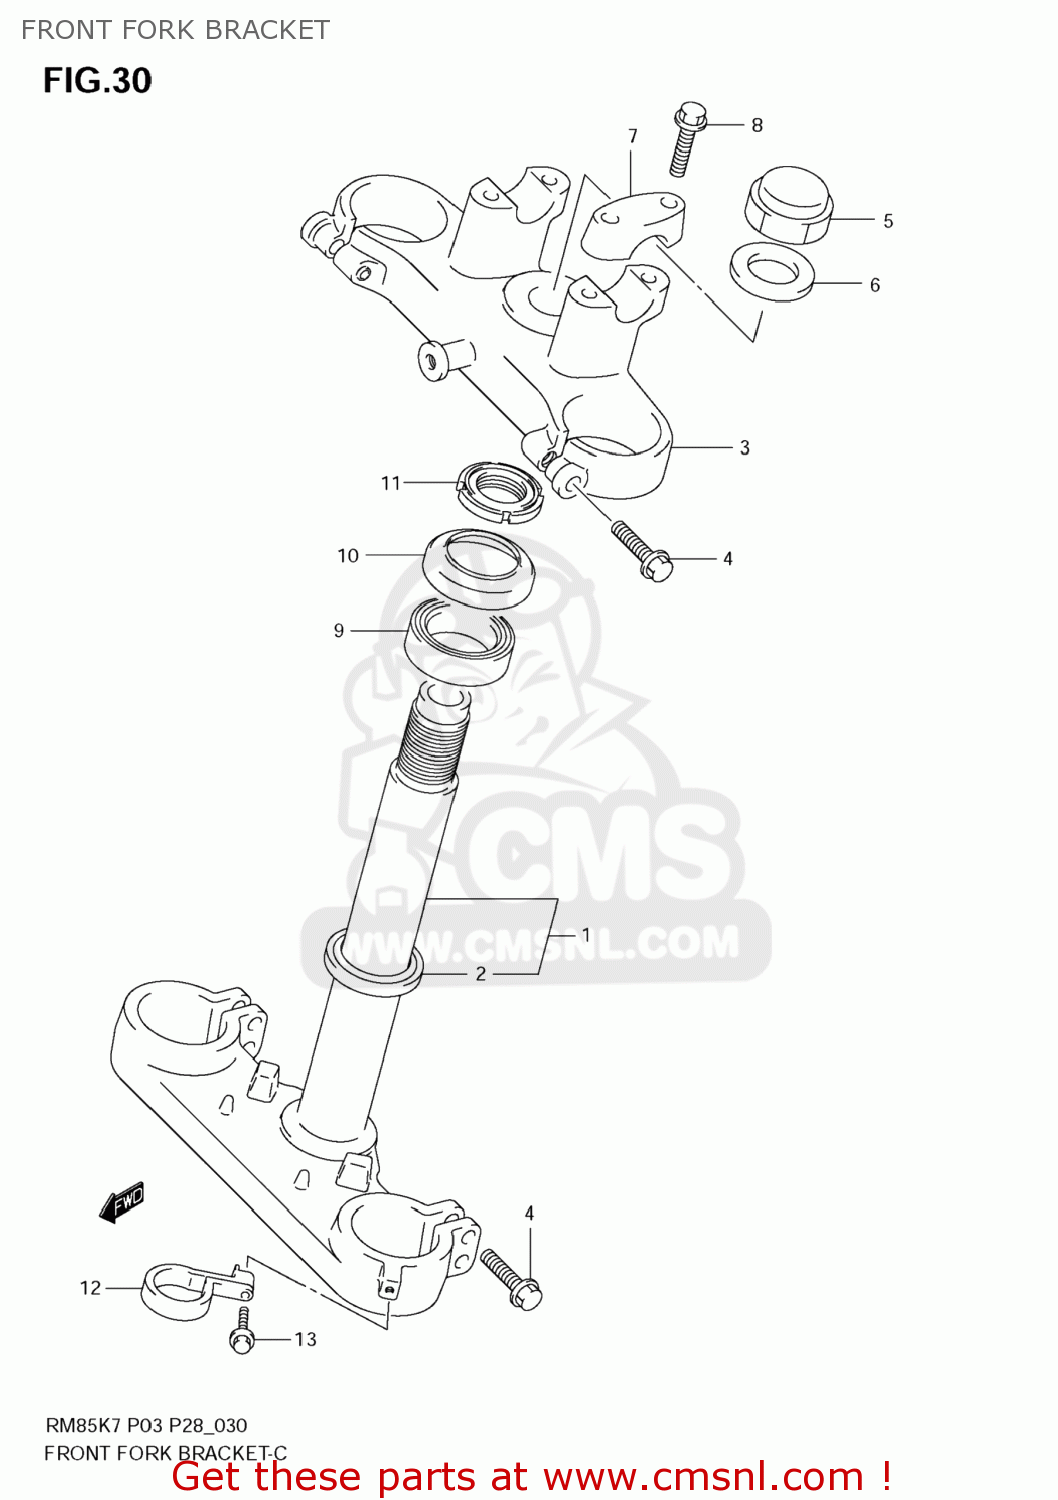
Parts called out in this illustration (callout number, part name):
1	STEM,STEERING
2	BEARING(26X47X15)
3	HEAD,STEERING STEM
4	BOLT
5	NUT
6	WASHER
7	HOLDER,HANDLE
8	BOLT
9	BEARING(25X47X15)
10	SEAL,STEERING UPR DUST
11	NUT,STEERING
12	GUIDE,FR BRAKE HOSE
13	BOLT
